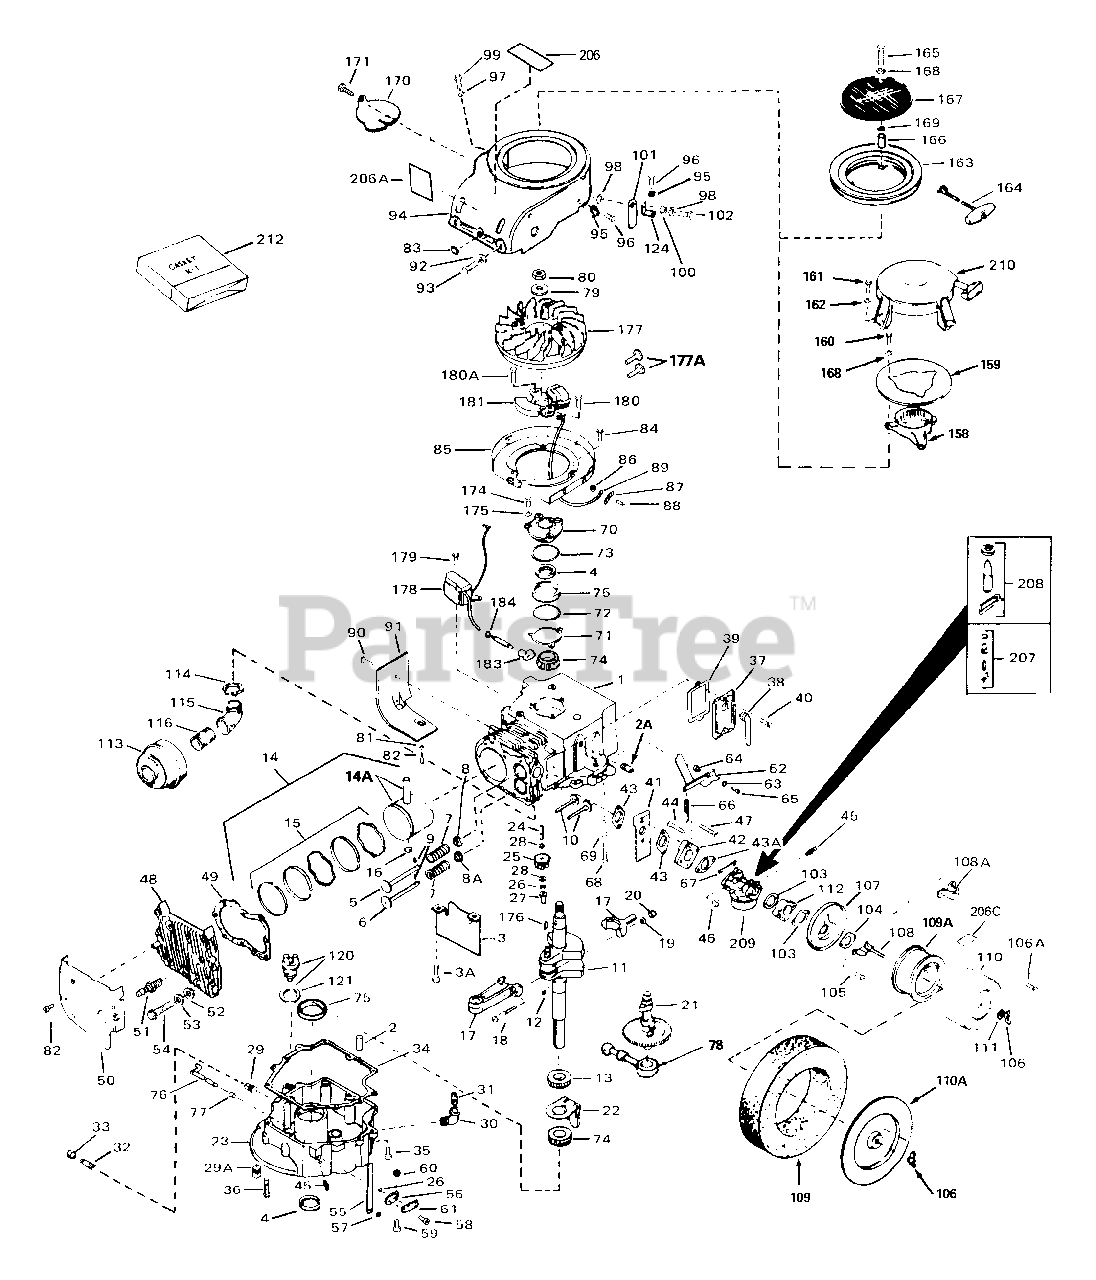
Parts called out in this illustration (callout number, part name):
1	"Cylinder Assy. (3-5/16" Bore)
2	Pin, Dowel
2A	Pipe plug 1/8-27 (Hex countersunk hea dless)
3	Baffle, Oil
3A	Screw, Fil. hd. Sems, 10-24 x 1/2
4	Seal, Oil
5	Valve, Intake (Std.)
5	Valve, Intake (1/32" oversize)
6	Valve, Exhaust (Std.)
6	Valve, Exhaust (1/32" oversize)
7	Spring, Valve
8	Cap, Valve spring (Std.)
8	Cap, Valve spring (1/32" oversize)
8A	Cap, Valve spring (Std.)
8A	Cap, Valve spring (1/32" oversize)
9	Pin, Valve spring retaining
10	Lifter, Valve
11	Crankshaft Assy.
12	Pin, Crankshaft gear
13	Gear, Crankshaft (Helical)
14	Piston, Pin & Ring Assy. (Std.) (3-5/ 16")
14	Piston, Pin & Ring Assy. (.010 oversi ze)
14	Piston, Pin & Ring Assy. (.020 oversi ze)
14	Piston, Pin & Ring Assy. (.040 oversi ze)
14	Piston, Pin & Ring Assy. (.030 oversi ze)
14A	Piston & Pin Assy. (Std.) (3-5/16")
14A	Piston & Pin Assy. (.010 oversize)
14A	Piston & Pin Assy. (.020 oversize)
14A	Piston & Pin Assy. (.030 oversize)
14A	Piston & Pin Assy. (.040 oversize)
15	Ring Set, Piston (Std.) (3-5/16")
15	Ring Set, Piston (.010 oversize)
15	Ring Set, Piston (.020 oversize)
15	Ring Set, Piston (.030 oversize)
15	Ring Set, Piston (.040 oversize)
16	Ring, Piston pin retaining
17	Rod Assy., Connecting (Std.)
17	Rod Assy., Connecting (.010 undersize )
17	Rod Assy., Connecting (.020 undersize )
18	Bolt, Connecting rod
19	Washer, Connecting rod bolt
20	Nut, Connecting rod
21	Camshaft Assy. (Mechanical Compressio n
23	Flange, Mounting
24	Shaft, Mechanical governor
25	Gear Assy., Governor (Helical)
26	Ring, Retaining
27	Spool, Governor
28	Washer, Flat
29	Plug, Oil drain (3/8-18 sq. hd.)
32	Nipple, Pipe
33	Cap, Nipple
34	Gasket, Mounting flange
35	Screw, Hex hd. Sems, 1/4-20 x 1
36	Screw, Hex hd. Sems, 1/4-20 x 2
37	Breather Assy.
38	Tube, Breather
39	Gasket, Breather
40	Screw, Fil. hd. Sems, 10-24 x 1/2
41	Baffle, Air
42	Flange, Carburetor
43	Gasket, Carburetor
43A	Gasket, Carburetor
44	Screw, Fil. hd., 1/4-28 x 7/8
46	Nut & Lockwasher Assy., 1/4-28
47	Screw, Fil. flex hd., 1/4-20 x 7/8
48	Head, Cylinder
49	Gasket, Cylinder head
50	Cover, Cylinder head
51	Plug, Spark (Champion J-8, Autolite 4 56 or
51	Resistor Spark Plug
52	Washer, Flat
53	Washer, Belleville
54	Screw, Hex hd., 5/16-18 x 1-5/8
55	Lever, Governor
56	Clamp, Governor lever
57	Lockwasher, #10
58	Screw, Hex washer hd. Sems, 10-32 x 1 /2
59	Screw, Pan flex hd., 10-24 x 7/8
60	Nut, Square, 10-24
61	Plate, Governor spring
62	Lever, Governor adjusting
63	Washer, Wave
64	Bushing, Governor lever
65	Screw, Hex washer hd., 10-24 x 5/8
66	Spring, Governor
67	Link, Governor
68	Screw, Fil. hd., 10-24 x 2
70	Cover, Cylinder
71	Gasket, Shim (.004/.005 thick)
71	Gasket, Shim (.005/.007 thick,)
72	Spacer, Steel (.010 thick)
73	"O" Ring
74	Bearing, Tapered roller
75	Cup, Bearing
76	Rod Assy., Governor
77	Spacer, Governor rod
78	Pump Assy., Oil
79	Washer, Lock
80	Nut, Flywheel
81	Washer, Flat
82	Screw, Fil. hd. Sems, 10-24 x 1/2
83	Plug, Button
84	Screw, Hex washer hd. Durlok, 1/4-20 x 5/8
85	Baffle, Blower housing
90	Screw, Hex hd. Sems, 1/4-20 x 1/2
90	Screw, Fil. hd. Sems, 10-24 x 1/2
91	Extension, Blower housing
92	Washer, Flat
93	Screw, Hex hd., 5/16-18 x 5/8
94	Housing, Blower
95	Clip, Conduit
96	Screw, Hex washer hd. Sems, 10-32 x 3 /8
97	Lockwasher, 5/16"
99	Screw, Hex hd., 5/16-24 x 3/8
100	Washer, Internal Lock, 5/16
102	Screw, Hex hd., 5/16-24 x 9/16
103	Gasket, Air cleaner
104	Spacer, Air cleaner
105	Screw, Fil. hd. Sems, 10-32 x 2
106	Nut, Wing
107	Bracket, Air cleaner
108	Bracket, Air cleaner
109A	Element, Air cleaner
110	Cover, Air cleaner
111	Washer, Fibre
112	Flange, Air cleaner
114	Nut, Conduit
115	Elbow, Exhaust (90(deg))
124	Bracket, Control
165	Screw, Truss hd., 1/4-20 x 3/4
166	Spacer, Screen
167	Screen, Starter pulley
168	Washer, Flat
169	Washer, Flat
170	Cover, Starter bubble
171	Screw, Hex washer hd. shakeproof,
174	Screw, Hex hd. Sems, 5/16-18 x 7/8
176	Key, Flywheel
177	Flywheel (Solid state)
177A	Trigger Pin Kit
183	Cover, Spark plug
184	Grommet, Lead wire
206	Decal, Instruction
206C	Decal, Instruction
208	Inlet Needle, Seat & Clip Assy.
209	Carburetor
212	Gasket set
